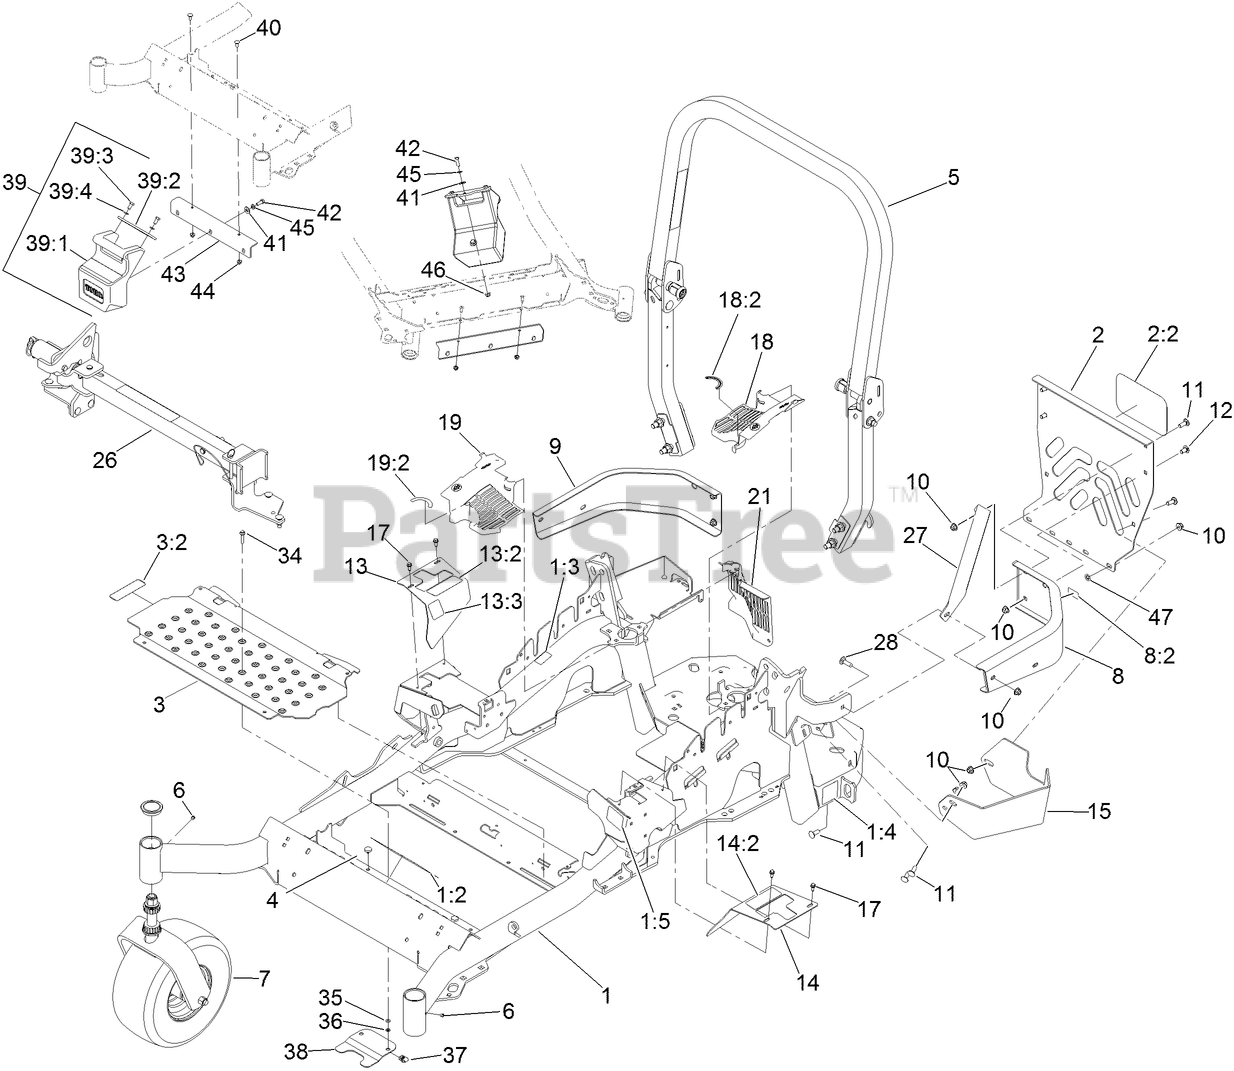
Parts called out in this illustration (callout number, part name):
1	MAIN FRAME ASM
1:2	DECAL-DANGER SLOPE W/ROPS
1:3	DECAL-WARNING
1:4	DECAL-HAZARD, PINCHED FINGER
1:5	DECAL-FUEL FILL, CE
2	REAR GUARD ASM
2:2	DECAL
3	FLOORPAN ASM
3:2	DECAL-MISSING, COVER
4	BUMPER
5	ROPS ASM
7	FRONT CASTER ASM
8	LH REAR BUMPER ASM
8:2	DECAL-WARNING
9	BUMPER-RH
10	NUT-HF, NI
11	SCREW-CARR
12	SCREW-CARR
13	RH MOTION CONTROL COVER ASM
13:2	DECAL-CONTROL, MOTION
13:3	DECAL-PARK BRAKE, CE
14	LH MOTION CONTROL COVER ASM
14:2	DECAL-CONTROL, MOTION
15	GUARD-MUFFLER
17	SCREW-HWH
18	LH HYDRO GUARD ASM
18:2	DECAL-HYDRO OIL
19	RH HYDRO GUARD ASM
19:2	DECAL-HYDRO OIL
21	GUARD-HYDRO, REAR (RH)
26	Z STAND ASM
28	BOLT-CARR
34	SCREW-HHF
35	WASHER-FLAT
36	NUT-RETAINER
38	ADAPTER-CAPTIVE
39	WEIGHT ASM
39:1	WEIGHT-43 LB
39:2	TAB-SUPPORT, WEIGHT
39:3	SCREW-HH
39:4	WASHER-LOCK
40	SCREW-CARR
41	WASHER-FLAT
42	SCREW-HH
43	BRACKET-MOUNT, WEIGHT
44	NUT-HF, NI
45	WASHER-LOCK
46	NUT-HF, NI
47	NUT-PUSH
